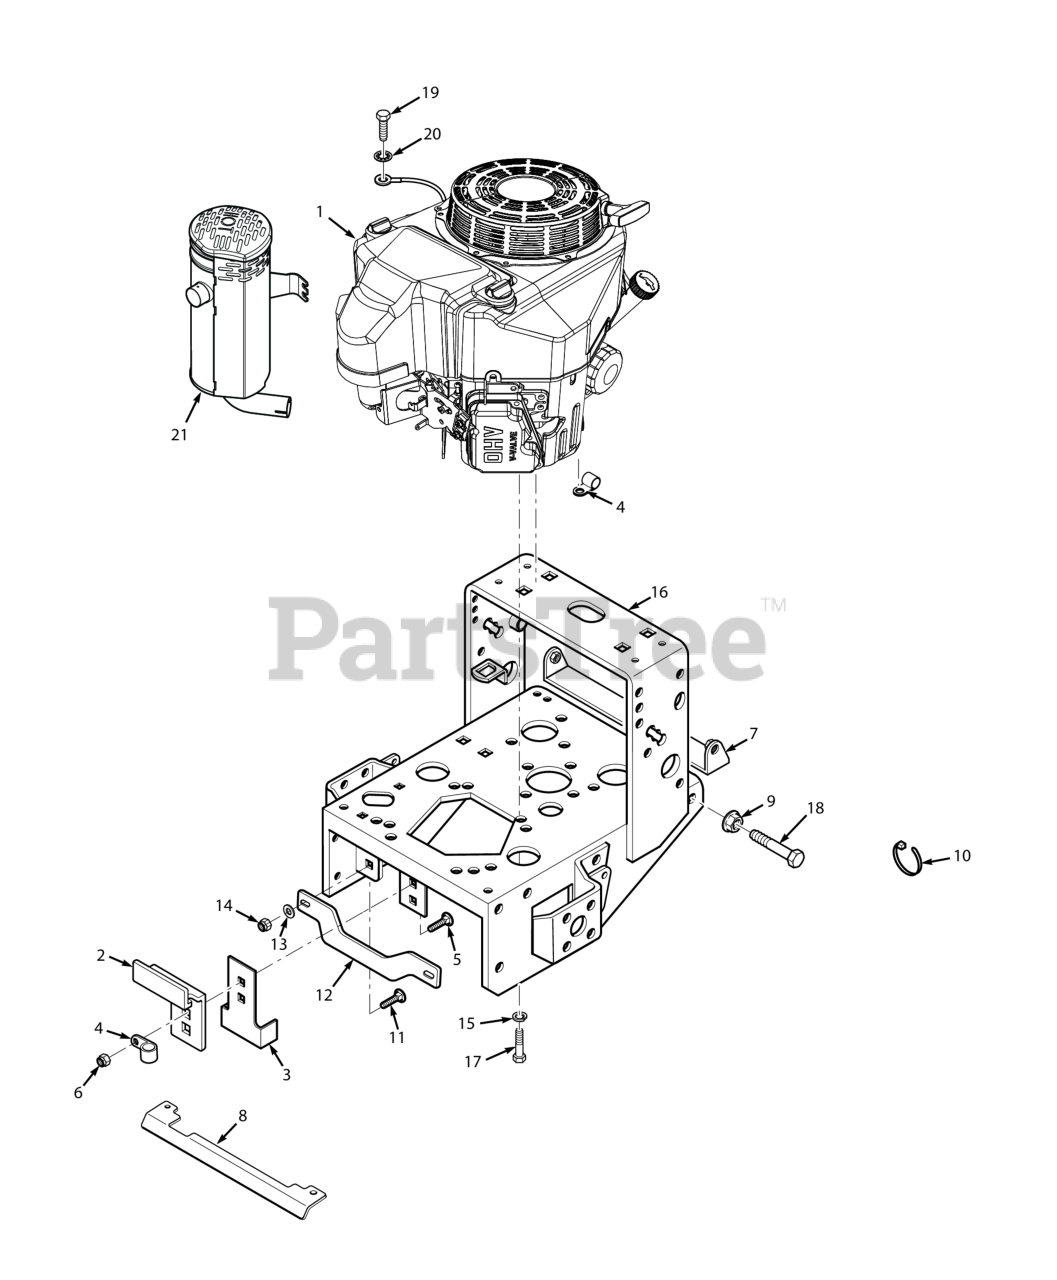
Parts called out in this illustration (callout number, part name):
2	Plate, Clutch Bracket
3	Plate, Clutch Anti-Rotation
4	Clamp, Cable 1/2" I.D.
5	Bolt, Carriage 5/16-18x1" (large frame units only)
6	HEX NUT, ELASTIC STOP LOCK, 5/16-18
7	Pulley Guard, 16" Small Frame
8	Heatshield, 16" Small Frame
9	Nut, Serrated Flange 5/16-18 (Right Front Engine Mounting, Briggs and Kohler Only)
10	Cable Tie, .19 x 8.0"
11	SHORT SQ. NECK CARRIAGE BOLT, 3/8-16 X 1-1/4"
12	Brace, (16" Small Frame)
13	Flatwasher, 3/8 (.391 x .938 x .105 HD) Grade 8
14	HEX NUT, ELASTIC STOP LOCK, 3/8-16
15	Lockwasher, 3/8" Spring, Kawasaki FX / FT & FT-EFI / B&S 32BV
16	Engine Deck (16" Wide) with Decals - Small Frame
17	Bolt, Hex Head 3/8-16 x 1-1/4", Kawasaki FX / FT & FT-EFI
18	Bolt, Hex Head 5/16-18 x 2-1/2" (x3) (35BV & 37BV-EFI)
19	Bolt, Hex Head M8 - 1.25 x 16 (48V / 52V)
20	Lockwasher, 5/16" Ext. Tooth (Kohler x1)
21	Muffler, Kawasaki (FS481, FS541, FS600)
